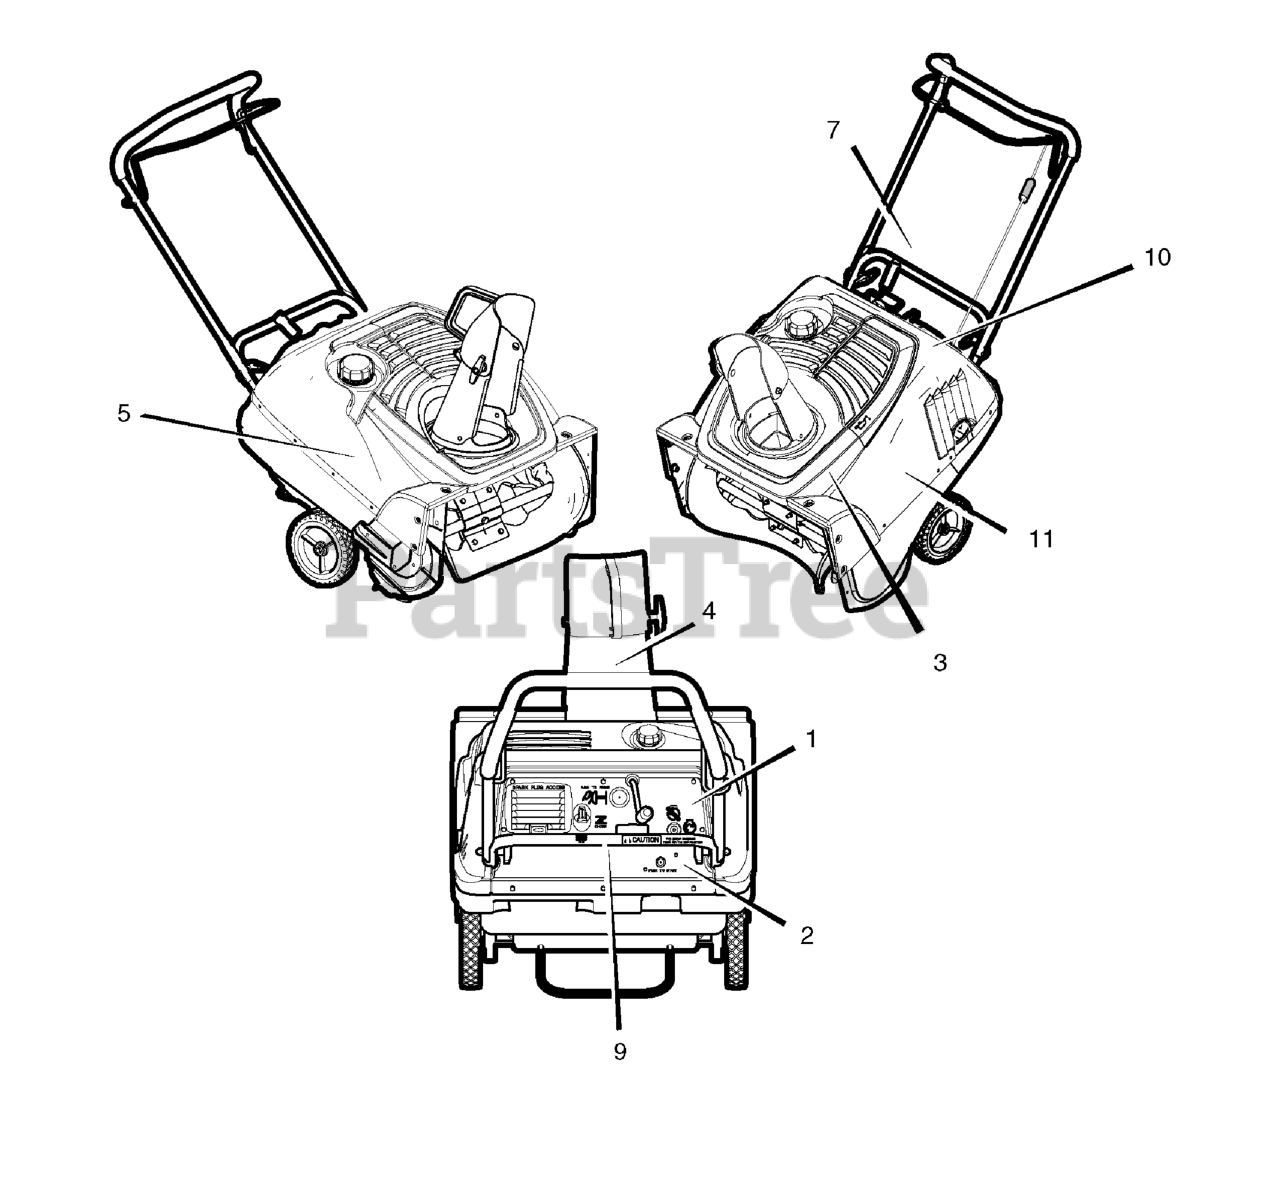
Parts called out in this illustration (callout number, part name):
1	Decal, Panel - 22" ES CANADA
2	Decal, Push To Start
3	Decal, Danger Auger
4	Decal, Danger Chute
5	Decal, 22" CRAFTSMAN ES, RH
7	Decal, Auger Control
9	Decal, Electric Plug Orientation
10	Decal, Warning, Access Cover
11	Decal, 22" Craftsman ES, LH
